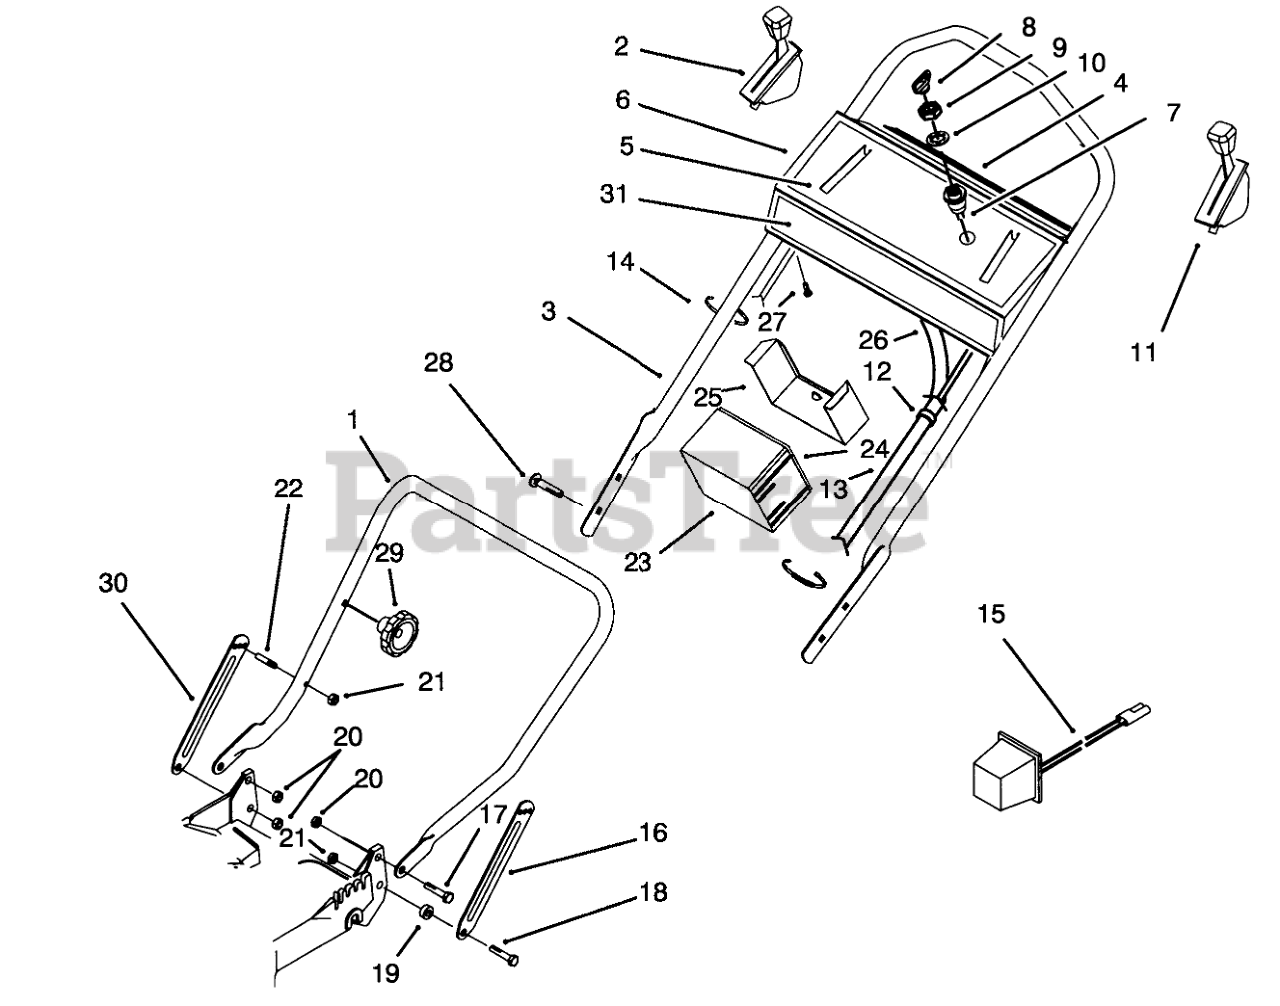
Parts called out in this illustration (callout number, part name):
1	LOWER HANDLE ASM
2	CONTROL-SPEED, GROUND
3	UPPER HANDLE, PVC DIP
4	DECAL - PANEL, REAR
5	DECAL - INSTRUCTION
6	Panel-Control (Incl. Ref. #4 & 5)
7	STARTER SWITCH ASM
8	KEY-IGNITION
9	NUT-HH
10	WASHER-TOOTH, INTERNAL
11	THROTTLE CONTROL
12	FITTING-RING
13	CONTROL CABLE COVER
14	TIE-CABLE
15	Charger
16	LH HANDLE LATCH
17	SCREW-SHOULDER
18	SCREW-SHOULDER
19	SPACER
20	NUT-LOCK, NI
21	NUT-LOCK, NI
22	HANDLE PIN
23	BATTERY ASSEMBLY
24	DECAL - BATTERY
25	Retainer-Battery
26	Harness-Wire
27	10-16X1/2 SHWH SCREW
28	5/16-18 X 2 HNDLE SCREW
30	RH HANDLE LATCH
31	DECAL - PANEL
